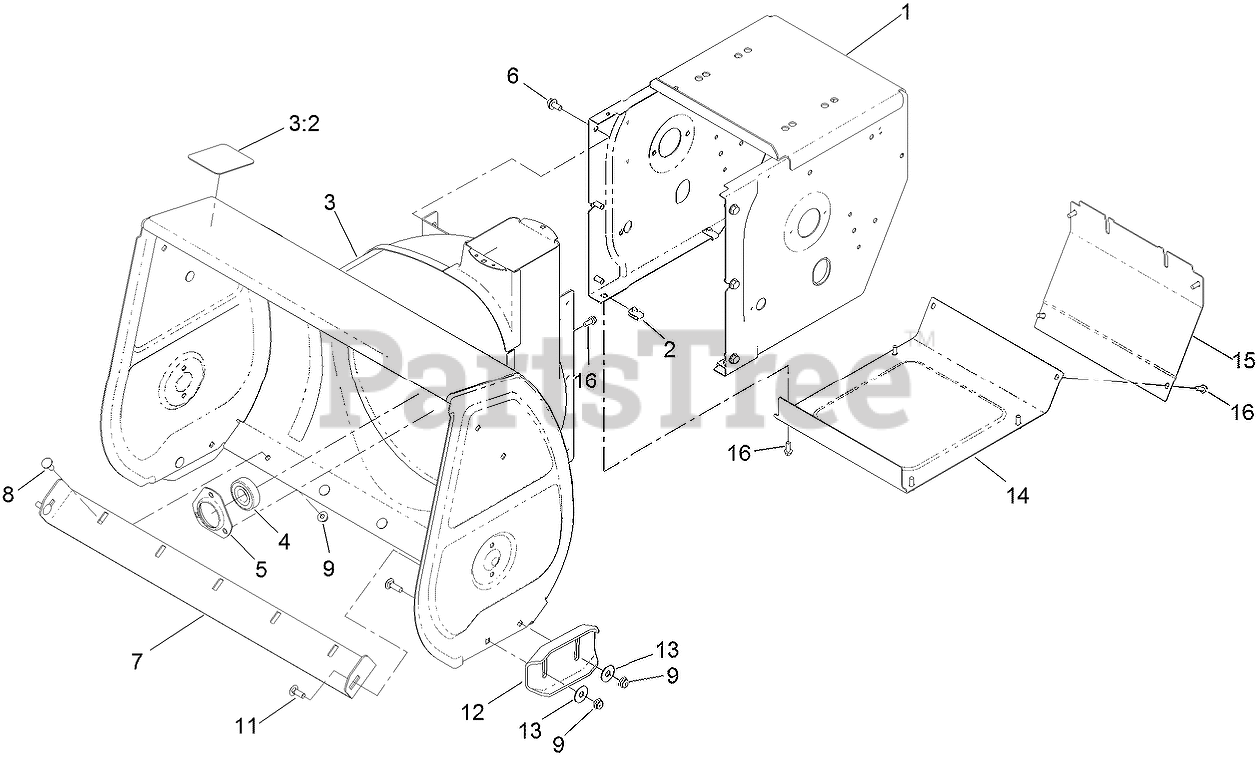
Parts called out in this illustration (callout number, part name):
1	FRAME-TRACTION
3	AUGER HOUSING ASM
3:2	DECAL-DANGER
4	BEARING-BALL
5	RETAINER-BEARING
6	SCREW-HWHTF
7	BLADE-SCRAPER
8	BOLT-CARR
9	NUT-HF
11	BOLT-CARR
13	WASHER-FLAT
14	COVER-BOTTOM
15	COVER-REAR
16	SCREW-HWH
